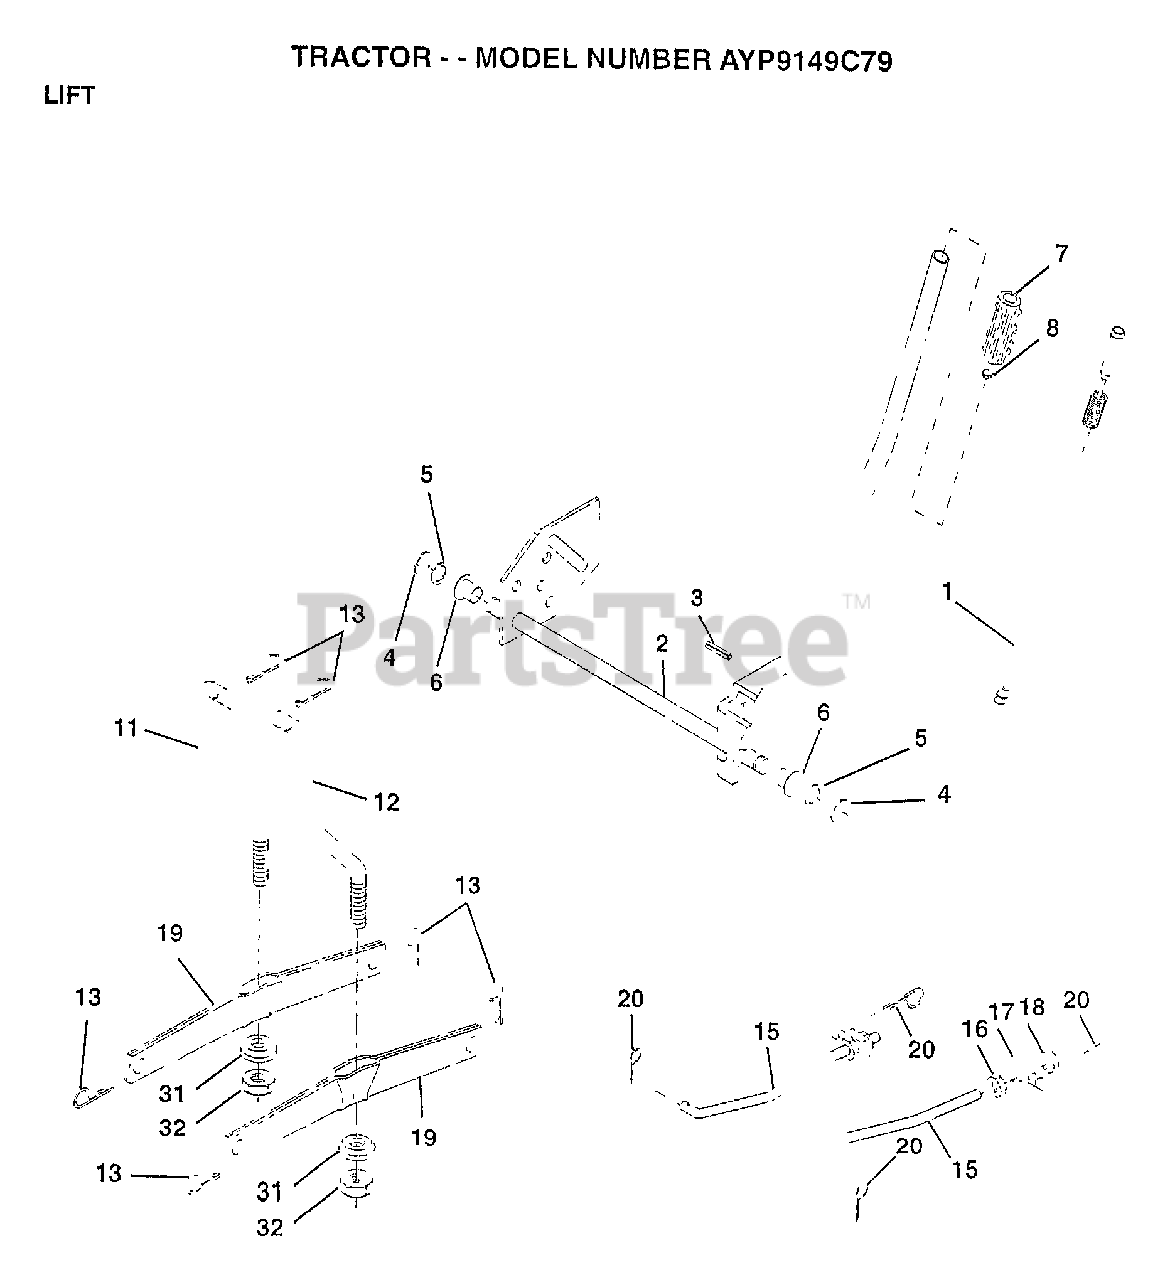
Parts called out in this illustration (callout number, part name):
1	WIRE ASM W.SPRING
2	"SHAFT ASM LIFT,RH"
3	PIN-GROOVE LT
5	WASHER
6	NYLON BEARING
7	GRIP
15	LINK.FRONT
16	NUT
17	TRUNION
18	NUT.LK.W/WSH.1/2.
19	ARM SUSP REAR
20	RETAINER.SPRING
31	BEARING PVT LH
32	NUT.CROWNLOCK.3/8
